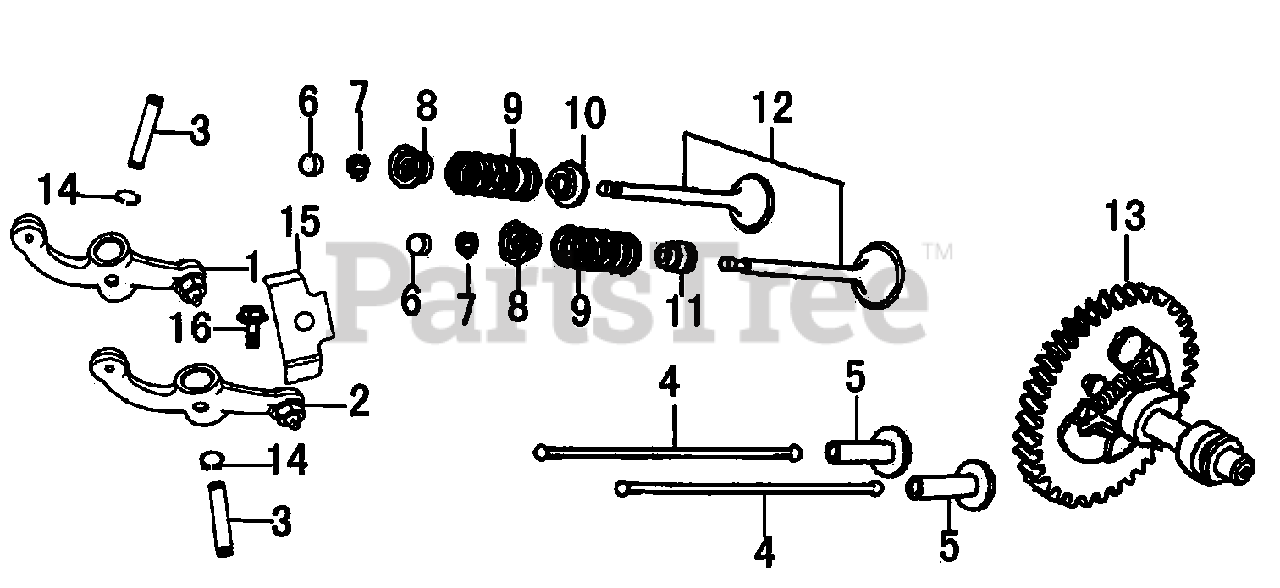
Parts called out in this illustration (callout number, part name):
1	ROCKER ARM ASSY.
2	ROCKER ARM ASSY.
3	SHAFT, VALVE ROCKER
5	LIFTER, VALVE(TAPPET)
6	ROTATOR, VALVE
7	LOCKER, VALVE
8	RETAINER, VALVE SPRING
9	SPRING, VALVE
10	SEAT, VALVE SPRING
11	SEAL, VALVE STEM
12	VALVE ASSY.
13	CAMSHAFT ASSY
14	CLIP, RKR ARM SHFT RETAINER
15	PLATE, RKR ARM SHFT RETAINER
16	BOLT, FLANGE
